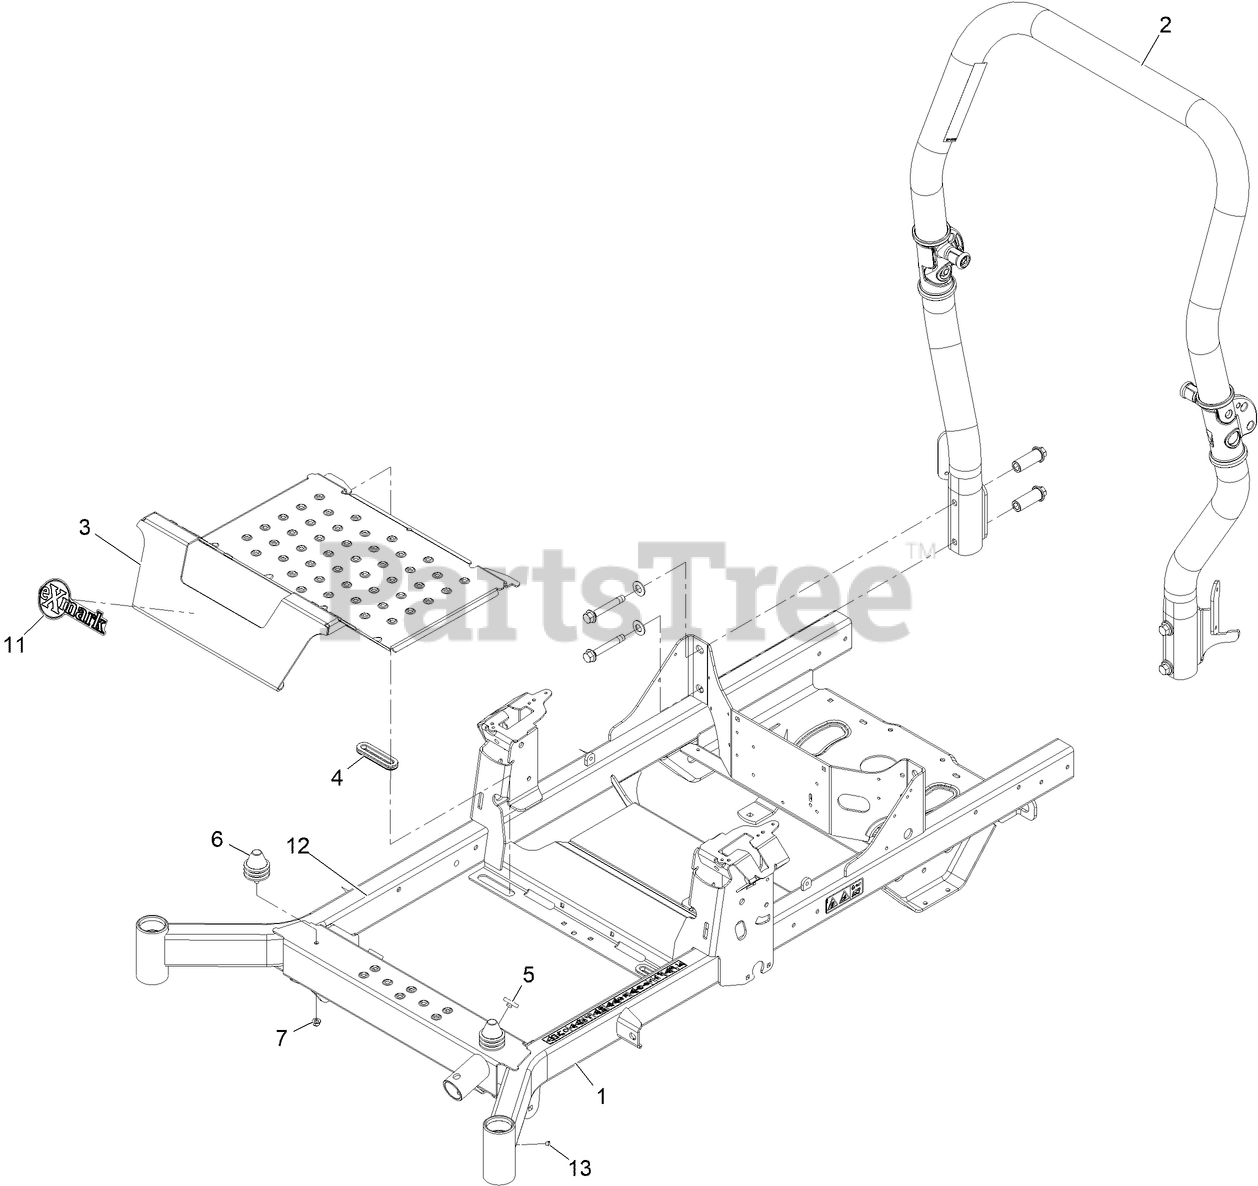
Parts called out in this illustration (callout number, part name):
1	ASM, Frame W/ Decal
2	ASM, ROPS
3	Pan-Floor
4	GROMMET-RUBBER
5	BUMPER-PUSH-IN, RUBBER
6	ISOLATOR
7	NUT-HF, NI
11	DECAL-EXMARK LOGO
12	Decal-Emissions,Epa 2023,Exmark
